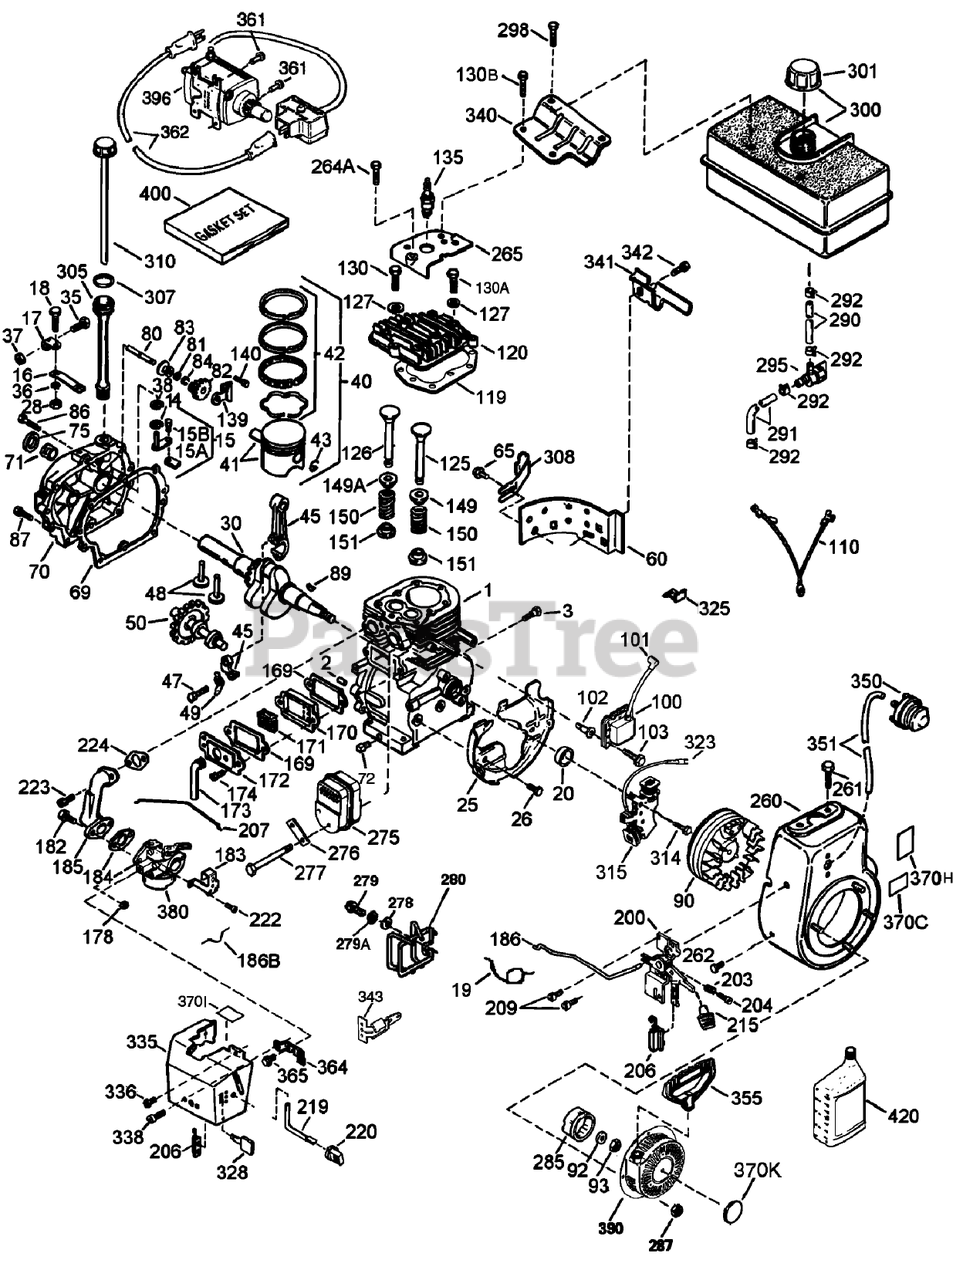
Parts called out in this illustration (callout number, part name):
203	Spring-Compression
204	Screw (T-10, 5-40x7/16)
206	Terminal
207	Link-Throttle
209	Screw (10-32 x 1/2)
215	Knob-Control
219	Rod-Choke
220	Knob-Control
222	Screw (10-32 x 1/2)
223	Screw (T-30, 5/16-18x1-3/32)
224	Gasket-Pipe, Intake
260	Housing-Blower
261	Screw (5/16-18x3/4)
262	Screw
264A	Screw (1/2-20x5/8)
265	Cover-Head, Cylinder (Black)
275	Muffler
276	62513 SNWTHWR W/284
277	Screw (5/16-18x4-3/16)
278	Washer-Flat
279	Screw (10-16 x 47/64)
279A	washer-Lock
280	Muffler Heat Shield ASM (Includes 278, 279, 279A)
285	Cup-Starter
287	Nut and Lock Washer (1/4-28)
290	Line-Fuel (8.62)
291	Line-Fuel
292	Clamp-Line, Fuel
295	Valve-Shut Off, Fuel
298	Screw (1/4-15x7/8)
300	Tank-Fuel (Includes 292, 301)
301	Cap-Fuel
305	Tube-Fill, Oil
307	O-Ring
308	Clip-Tube, Fill
310	Gauge Oil ASM
314	Screw (1/4-20 x 3/4)
315	Coil-Alternator, 18 Watt (Includes 323)
323	Terminal
325	Clip-Wire
328	Key-Ignition
329	Terminal
335	Cover-Carburetor (Black)
336	Screw (10-32x1/2)
338	Screw (10-32 x 3/8)
340	Bracket-Tank, Fuel (Black)
341	Bracket-Tank, Fuel
342	Screw (1/4-20x19/32)
343	Bracket-Switch, Key
343A	Screw (8-32 x 23/64)
350	Primer ASM
351	Line-Primer
355	Handle-Starter, Mitten Grip
361	Screw (T-30, 1/4-20x15/32)
364	Bracket-Carburetor
365	Screw (8-32x27/64)
370C	Decal-Primer, International Symbol
370H	Decal-Speed Control and Choke
370I	Decal-Warning (Bilingual)
370K	Decal-Tecumseh Logo for Top of Recoil Starter
371D	Decal-Instruction
380	Carburetor ASM
390	Starter-Rewind
396	Electric Starter Motor ASM (220 Volt)
400	Gasket Set (Includes 69, 119, 169, 184, 224)
420	Oil-Engine, S A E 5W30
